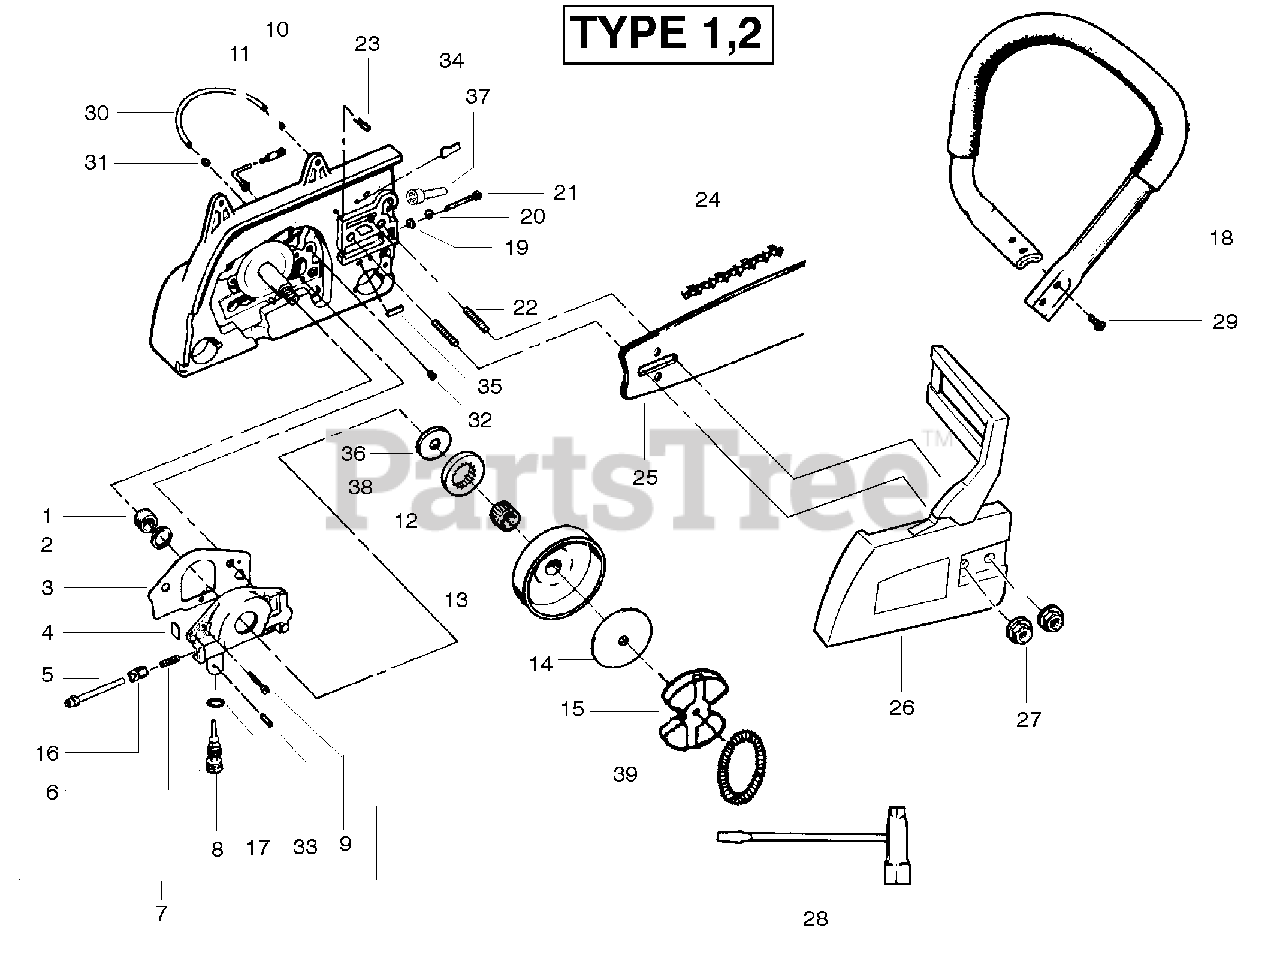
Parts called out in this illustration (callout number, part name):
1	Wire Worm Gear
2	Seal-Oil Pump
3	Gasket - Oil Pump
4	Dust Plug
5	Shaft Ass'y.
6	Spring-Plunger
7	Oil Pump Ass'y.
8	Screw Oiler Adjusting
9	Screw
10	Oil & Filter Pickup
11	Oiler Intake Line
13	Drum & Adaptor Ass'y.
14	Clutch Plate
15	Clutch Ass'y.
16	Gear Spur
17	"O" Ring
18	Handlebar Ass'y.
19	Guide Bar Pin
20	Retainer-Bar Adjust
22	Bar Stud
23	Cotter Pin
24	Chain (20")
24	Chain (22")
25	Bar (20")
25	Bar (22")
26	Chain Brake Kit
27	Nut-Bar Mounting
28	Scrench (Silver finish (1/2" x 3/4"))
28	Scrench (Gold finish (9/16" x 3/4"))
30	Oiler Line
32	Nut-Slotted Tube
33	Pin-Adjustment Screw
34	Chain Pad - Top
35	Chain Pad
36	Thrust Washer
37	Crankcase Plug
38	Rim Floating (3/8)
39	Spring - Clutch
